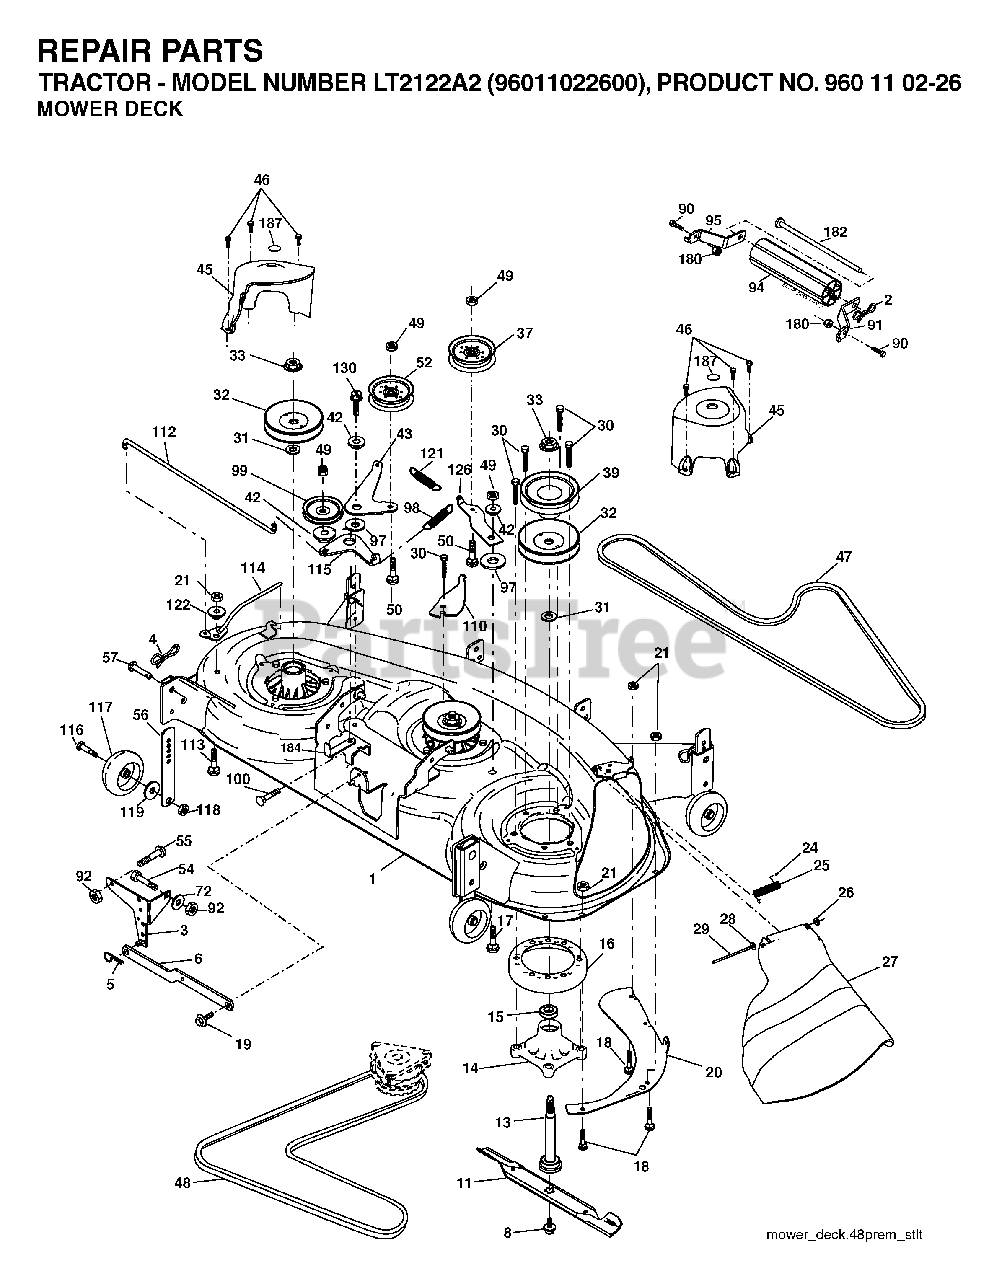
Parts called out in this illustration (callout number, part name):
1	DECK WELDMENT
2	PIN.COTTER.7/16.BOW TI
3	BRKT ASM SWAY BAR
4	PIN.COTTER.5/16.BOW TI
5	RETAINER-SPRNG RB
6	BAR SWAY DECK
8	BOLT 7/16 ASM BLADE
11	48" HI-LIFT BLADE
13	SHAFT ASM W/LOWER BEARING
14	HOUSING, MANDREL 48"
16	STRIPPER, MWR ROUND
17	BOLT
18	BOLT
19	BOLT SHD 5/16-18
20	BAFFLE, VORTEX MWR
21	LOCKNUT
24	CAP-SLEEVE LT
25	SPRING, TORSION
26	NUT PUSH M
27	DEFLECTOR SUBS TO 532 180655
28	WASHER
29	ROD.HINGE
30	SCREW, WASHER HEAD
31	WASHER.SPACER.MANDREL
32	PULLEY/MANDREL
33	NUT.FLANGE.LOCK.TOP
37	PULLEY.IDLER.48"PRIMARY
39	PULLEY.IDLER.DRIVEN
42	SPACER.RETAINER.MOWER
43	ARM, IDLER SECONDARY
45	COVER.MANDREL.DECK.48"
46	SCREW.1/4-20X5/8
47	V-BELT, 48"SECONDARY
48	V-BELT PRIMARY 48"
49	NUT LOCK FLG 3/8-16 UNC
50	BOLT.3/8-16X1.50
52	PULLEY.IDLER.FLAT.UNPLATED
54	BOLT
55	BOLT D
56	BAR.ADJUST.WHEEL.ANTI.SCALP.BL
57	RIVET.PIN.HEAD.YELLOW
72	WASHER
90	BOLT RB
91	BRKT.NOSEROLLER.RH.48"
92	NUT
94	NOSE ROLLER 48"
95	BRKT.NOSEROLLER.LH.48"
98	SPRING PRIMARY DRIVE
99	PULLEY.V.IDLER
100	BOLT
110	ARM, SPRING SECONDARY
112	LEVER, TENSION RELIEF LINK
114	LEVER ASM, TENSION RELIEF
115	ARM, SPRING TENSION RELIEF
116	BOLT.SHOULDER.3/8-16X3-5/8
117	WHEEL. GUAGE RALLY
118	LOCKNUT
119	WASHER
121	SPRING SECONDARY DR
122	BUSHING, PIVOT TENSION RELIEF
126	ARM, IDLER PRIMARY DECK
130	SCREW 3/8-16X1
180	NUT.71038.31-18.HEX.NYLOCK
182	ROD.ROLLER.NOSE.NARROW.48"
184	KEEPER BELT IDLER PLATED
